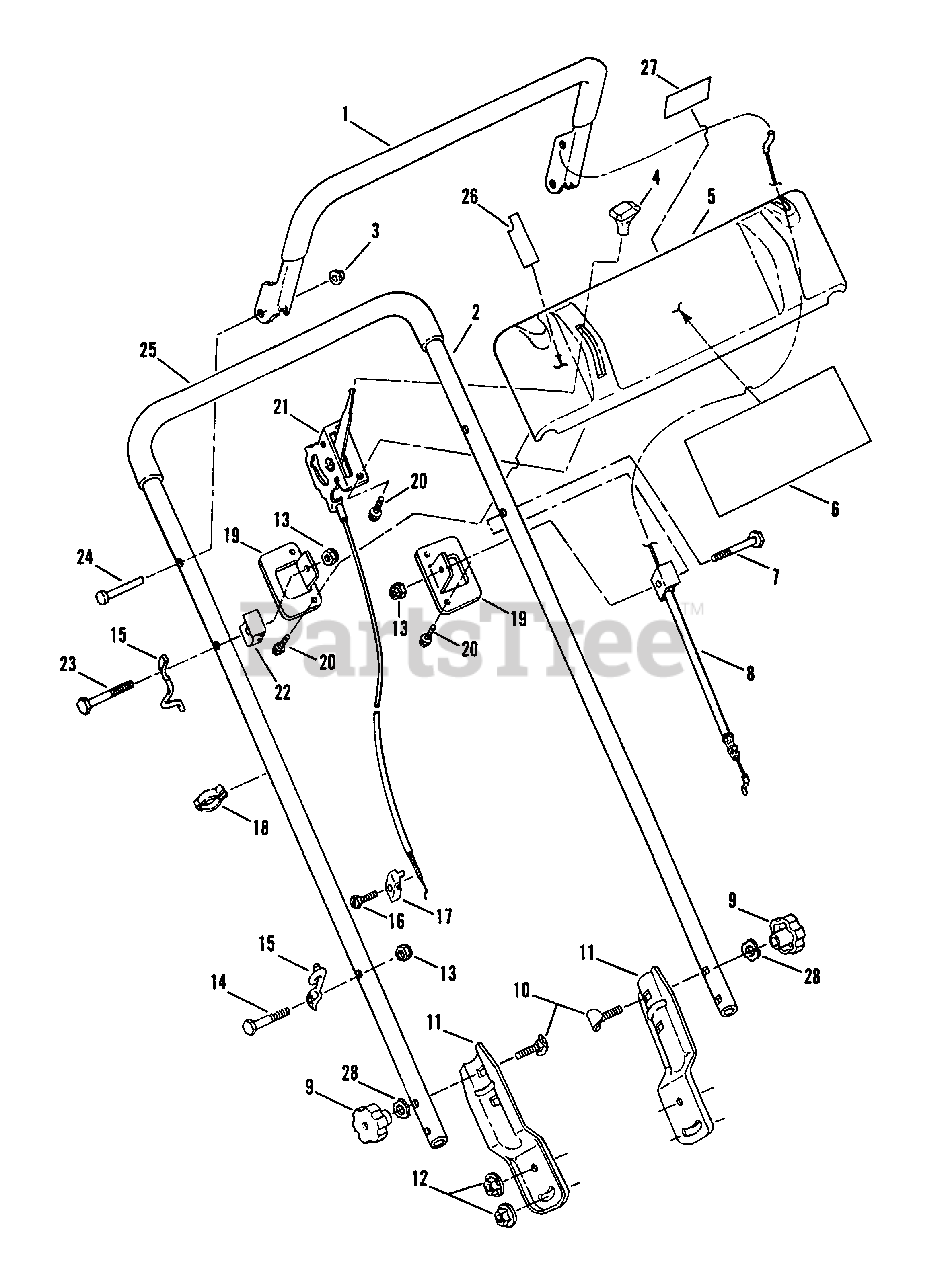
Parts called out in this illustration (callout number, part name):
1	CONTROL, Blade
2	HANDLE, Upper
3	PUSH-NUT, 5/16
4	KNOB, Throttle Control
5	CONSOLE, Control
6	DECAL, Console
7	SCREW, 1/4-20 x 2" Hex Head Cap, Grade 5
8	CABLE ASSEMBLY, Blade Control
9	KNOB, 5/16-18
10	SCREW, 5/16-18 x 2" Curved Head
11	BRACKET, Handle
12	NUT, 5/16-18 Hex Flange Lock
13	NUT, 1/4-20 Hex Nyloc
14	SCREW, 1/4-20 x 1 1/2" Hex Head Cap, Grade 5
15	GUIDE, Rope
16	SCREW, #10-32 x 5/8" Slotted Hex Head, Self-Tapping
17	CLAMP, Throttle Control
18	CLAMP, Cable
19	BRACKET, Console
20	SCREW, #10-16 x 1/2" Hex Washer Head, Self-Tapping
21	CONTROL, Throttle
22	FITTING, Handle Bar
23	SCREW, 1/4-20 x 2-1/4" Hex Head Cap, Grade 5
24	PIN, 5/16 x 1-23/64" Clevis
25	GRIP, Foam
26	DECAL, Throttle Control
27	DECAL, Instruction
28	WASHER, 5/16 Internal Tooth Lock
